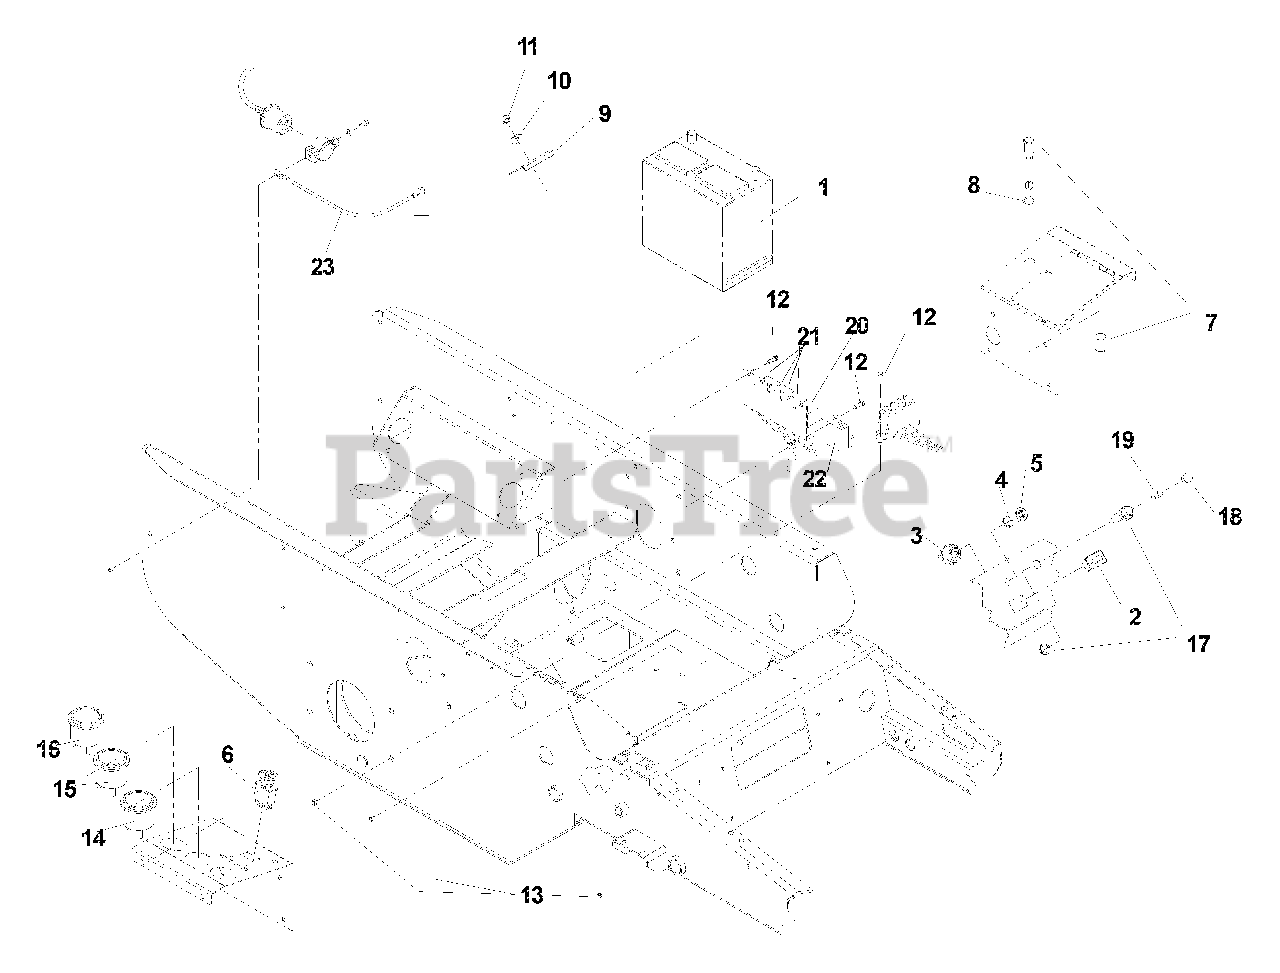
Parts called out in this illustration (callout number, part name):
2	Hourmeter, LCD w/flash alert
3	Switch, ignition
4	Nut, ignition switch
5	Cap, ignition switch nut
6	Switch, clutch
7	Power source housing
8	Power source cap
10	Washer, 5/16
11	Nut, 5/16-18
12	Bolt, , #10-24 x 3/4
13	Nut, #10-24, nyloc
14	Gauge, temperature
15	Gauge, amperes
16	Gauge, oil pressure
17	Lamp socket
20	Relay, Glow Plug
22	Timer/glow plug
